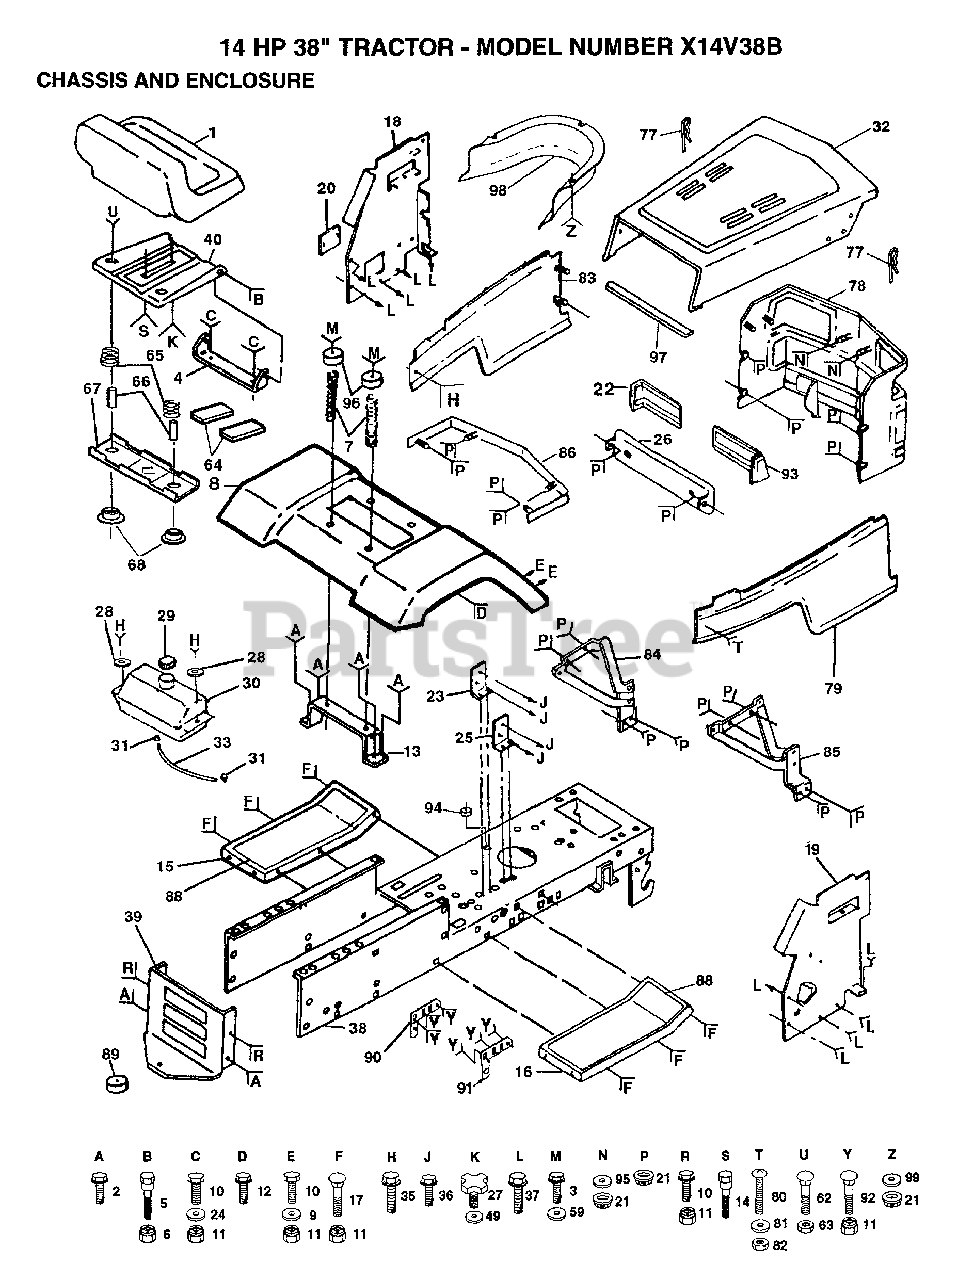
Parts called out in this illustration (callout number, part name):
2	SCREW
3	SCREW GTV
7	SPRING COMPRESSIO
9	WASHER
12	SCREW LT
14	"BOLT,SHOULDER"
17	BOLT
18	PANEL DASH LH
20	COVER ACCESS
21	PAL NUT LT
23	SWITCH BRACKET
24	WASHER
25	BRACKET LT
27	"KNOB 1/2"" YT"
28	WASHER
30	TANK.FUEL.LT.
31	HOSE CLAMP
35	SCREW HEX CRT
36	SCREW
37	SCREW LT
39	DRAWBAR LT/YT
49	WASHER
59	WASHER
64	STRIP FORM
65	SPRING
66	SPACER SPLIT
67	BRKT SWITCH
68	BUSHING
77	SPRING.RETAINER
79	SIDE PANEL ASM. RH
80	"SCREW,SPECIAL"
82	RETAINER
83	"SIDE PANEL,LH"
84	"HINGE,HOOD,LH T"
85	"HINGE,HOOD,RH T"
88	FOOTREST PAD
90	BRKT ASM PIVOT LH
91	BRKT ASM PIVOT RH
92	BOLT
94	SNAP BUSHING T
95	WASHER PM
96	CAP SPRING
97	FOAM-STRIP LT
99	WASHER
